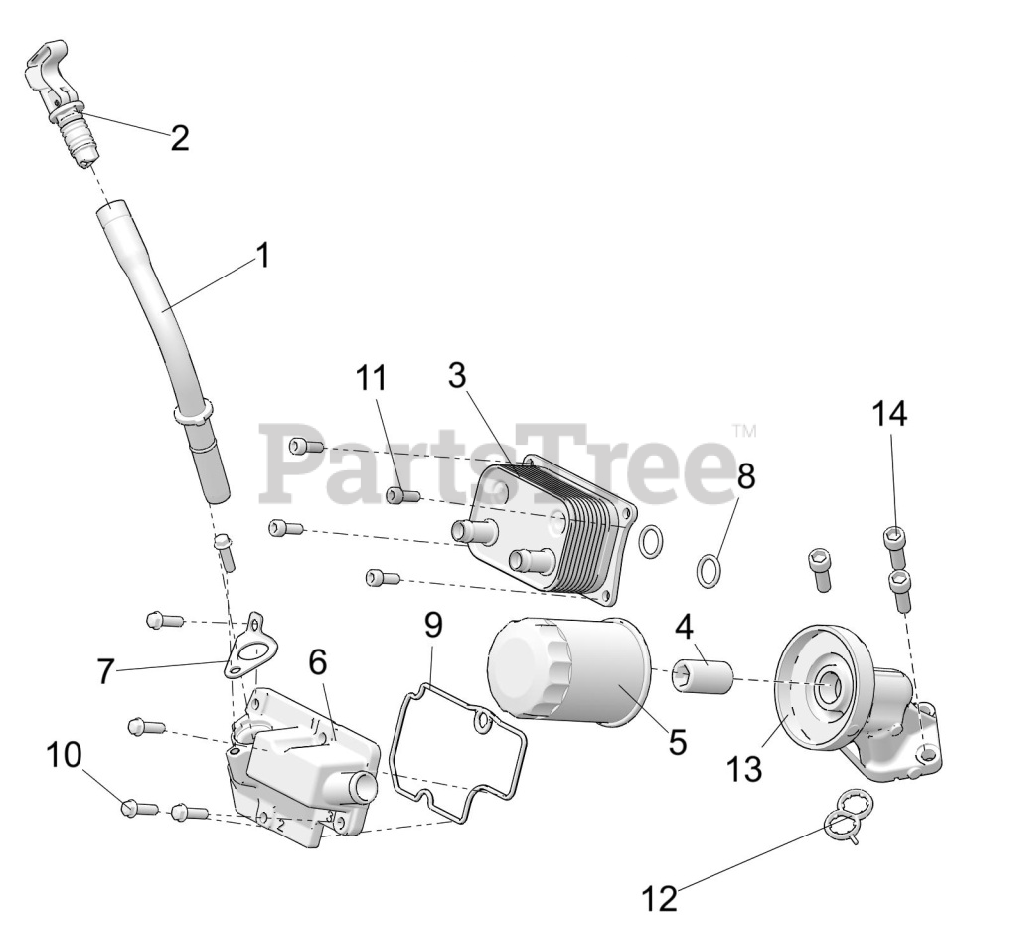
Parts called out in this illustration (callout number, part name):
1	ASM-OIL FILL TUBE
1	O-RING 12MM X 2MM
2	ASM-DIPSTICK
3	COOLER-OIL TO WATER-5
4	ADAPTER-FILTER-STRAIGHT
5	FILTER-OIL-10 MICRON-(12)
6	COVER, BREATHER
7	BRACKET, TUBE, OIL FILL, LOWER
8	O-RING-.612X.818X.103
9	SEAL-COVER-BREATHER
10	SCR-M6X20-HXFLG-0600214
11	SCR-SH-M6X1.0X16 8.8 ZPY D2O4
12	SEAL-FILTER ADAPTER-3 HOLE
13	ADAPTER-OIL FILTER- MACH
14	SCR-SH-M8X1.25X25 8.8 ZPC NYL
